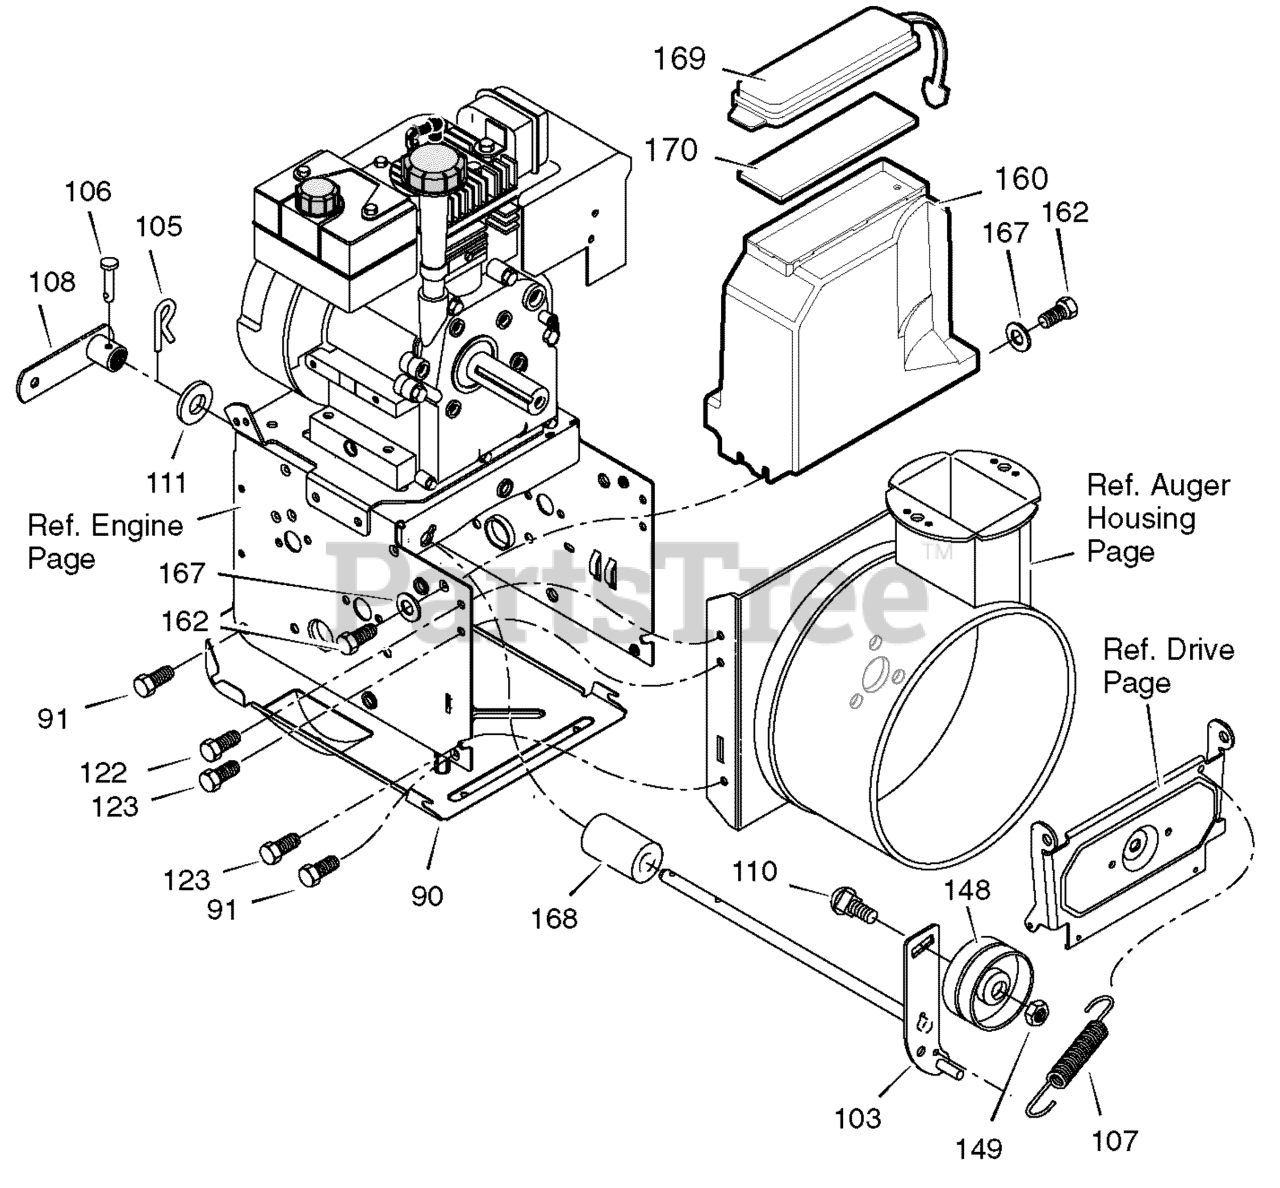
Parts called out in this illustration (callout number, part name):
90	COVER, BOTTOM
91	SCREW
103	IDLER, AUGER
105	PIN, HAIR
106	PIN, CLEVIS
107	SPRING, TENSION
108	SPRING ATTACH
110	BOLT, CARR.
111	WASHER, FLAT
122	SCREW, TAP
123	SCREW, TAP
148	PULLEY, IDLER
149	NUT, JAM 3/8-16
160	COVER, BELT
162	SCREW, TAP
166	WASHER, FLAT
168	SPACER
169	LID, TOOL BOX
170	PAD, FOAM
